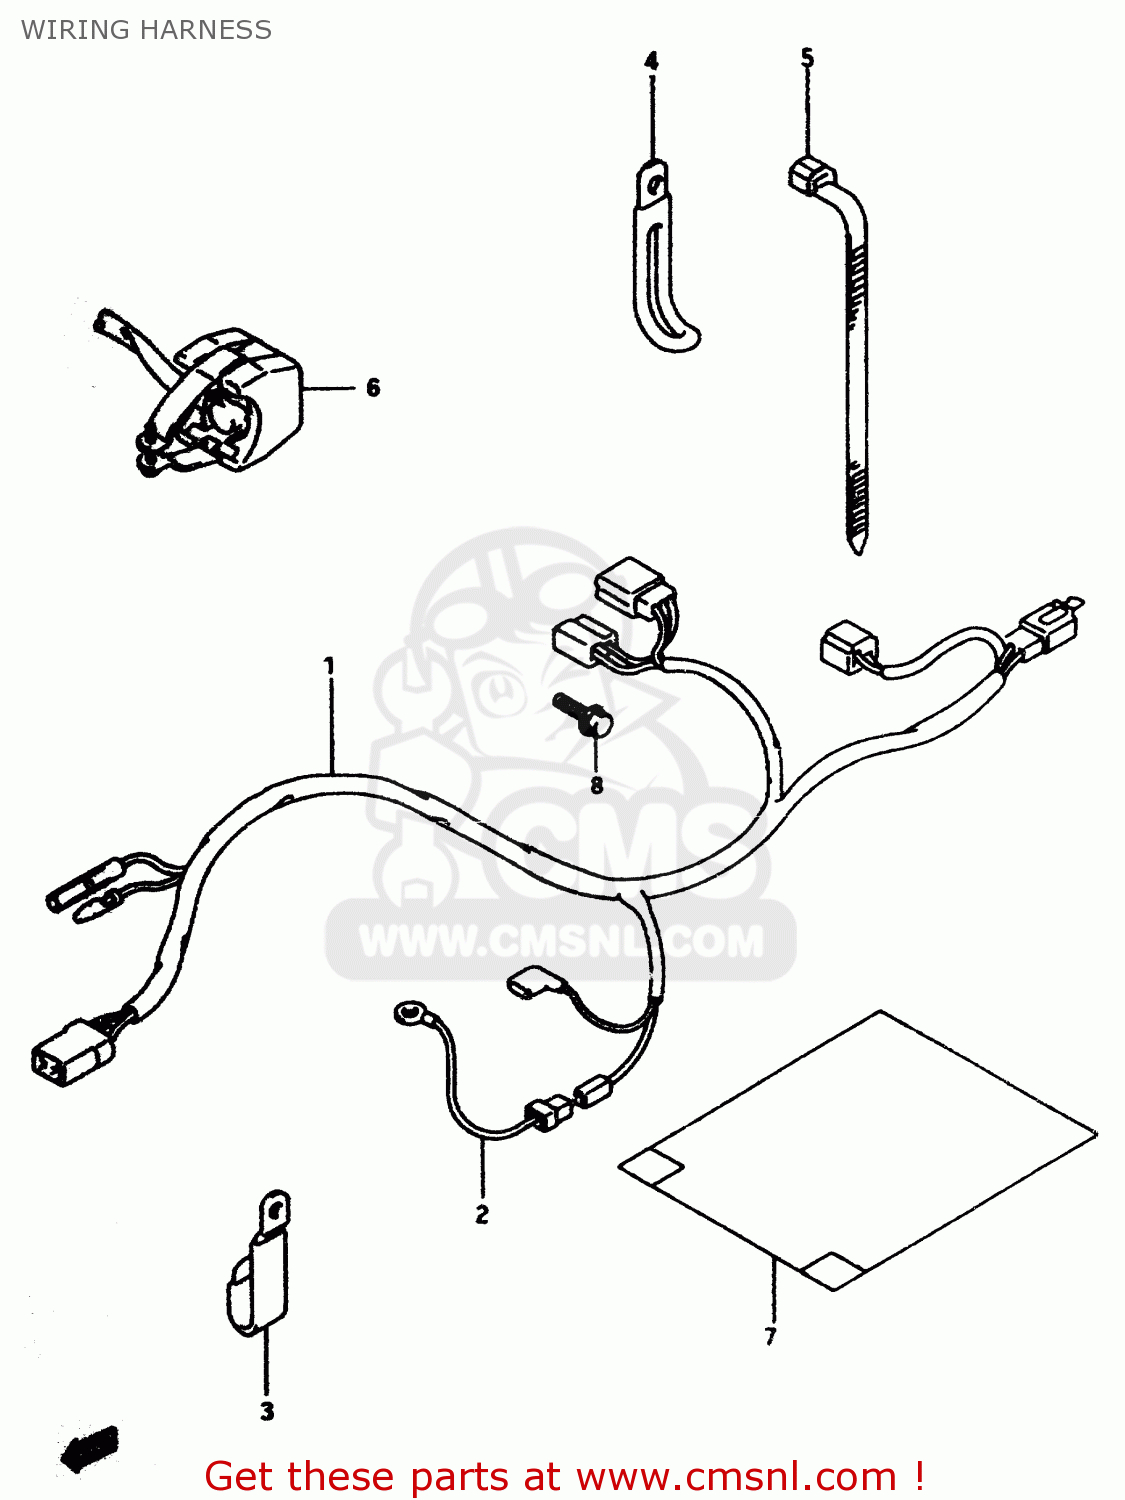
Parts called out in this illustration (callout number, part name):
1	HARNESS,WIRING
2	WIRE,REGULATOR EARTH LEAD
3	CLAMP
4	CLAMP L:62
5	CLAMP(L:95)
6	SWITCH ASSY,ENGINE STOP
7	COVER,HARNESS
8	BOLT
